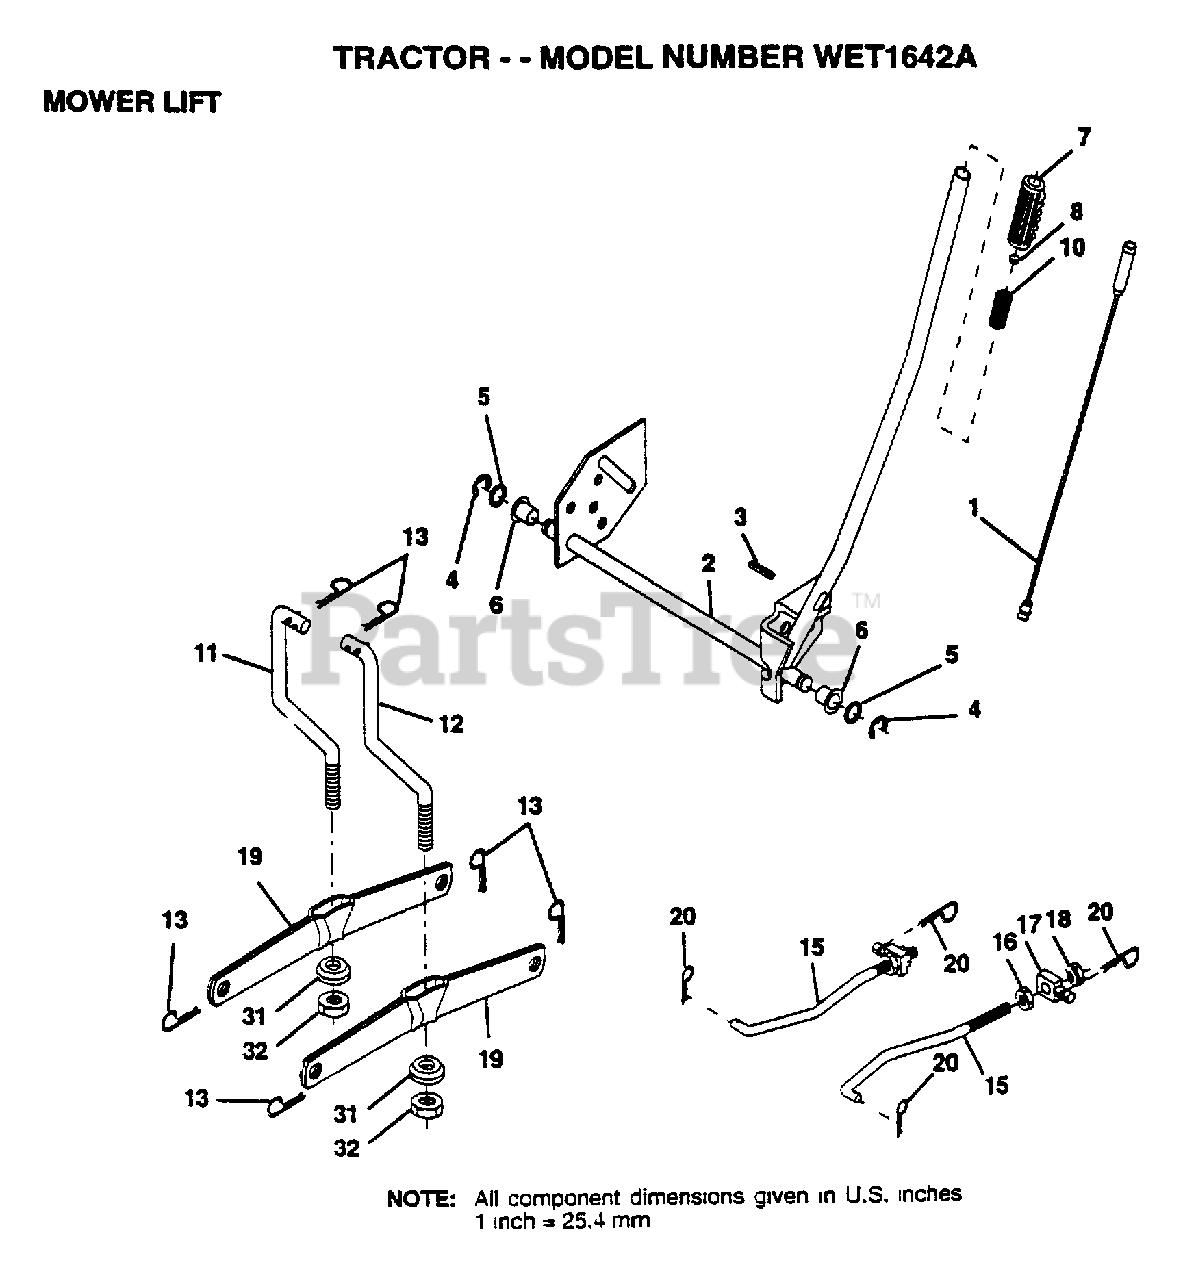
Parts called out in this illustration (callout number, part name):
1	WIRE ASM
3	PIN-GROOVE LT
5	WASHER
6	NYLON BEARING
7	GRIP
15	LINK.FRONT
16	NUT
17	TRUNION
18	NUT.LK.W/WSH.1/2.
19	ARM SUSP REAR
20	RETAINER.SPRING
31	BEARING PVT LH
32	NUT.CROWNLOCK.3/8
